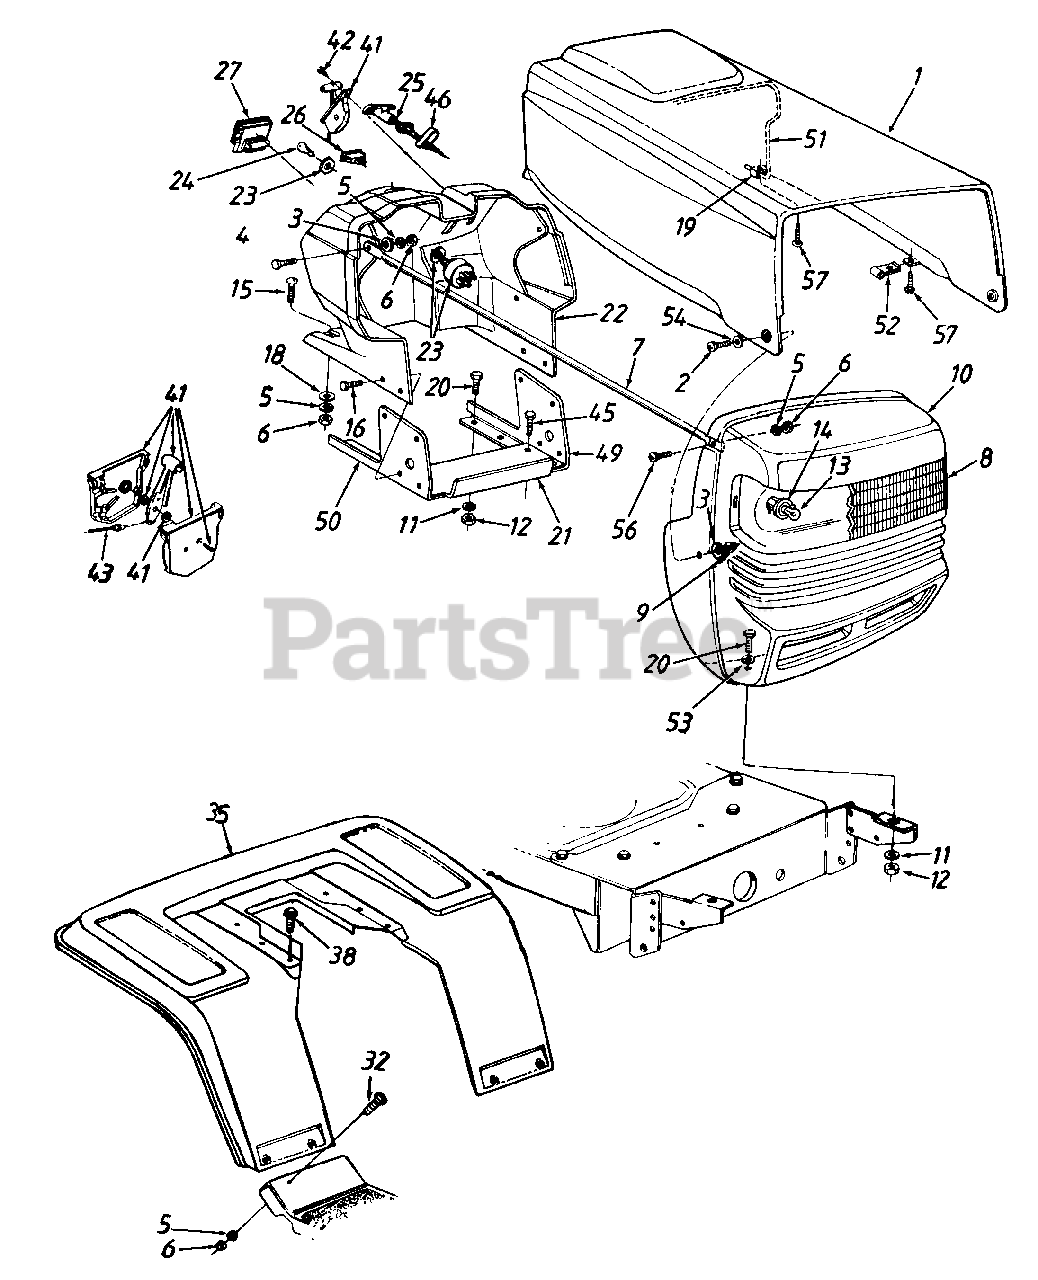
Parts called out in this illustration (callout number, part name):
3	Fl-Wash. .28" I.D. x .75" O.D.
4	Hex Bolt 1/4-20 x .88" Lg.
5	L-Wash. 1/4" I.D.
6	Hex Nut 1/4-20 Thd.
9	Flange L-Nut 1/4-28 Thd.
12	Hex Nut 5/16-18 Thd.
13	Lamp
14	Socket
15	Carriage Bolt 1/4-20 x .75" Lg.
16	Hex Wash. Hd. TT-Tap Scr. 1/4-20 x .5" Lg.
18	Bolt Retainer 1/4" I.D.
19	Speed Nut #10-24 Thd.
20	Hex Bolt 5/16-18 x .75" Lg.
23	Ignition Switch
24	Ignition Key
25	Choke Control
26	Light Switch
27	Ammeter
32	Truss Mach. Scr. 1/4-20 x .5" Lg.
41	Throttle Box Ass'y.
42	Truss Mach. AB-Tap Scr. #10 x 5" Lg.
43	Throttle Control Wire
45	Hex Wash Hd B-Tap Scr. 5/16-18 x .5" Lg.
46	Choke Retainer
52	Flat Fastener (Special)
53	Fl-Wash .344" I D. x 1" O.D.
54	Spr. Wash. .39" I.D. x .62" O.D.
56	Pan Hd. Scr 1/4-20 x .75" Lg.
57	Truss Mach. Scr. #10-24 x .5" Lg.
